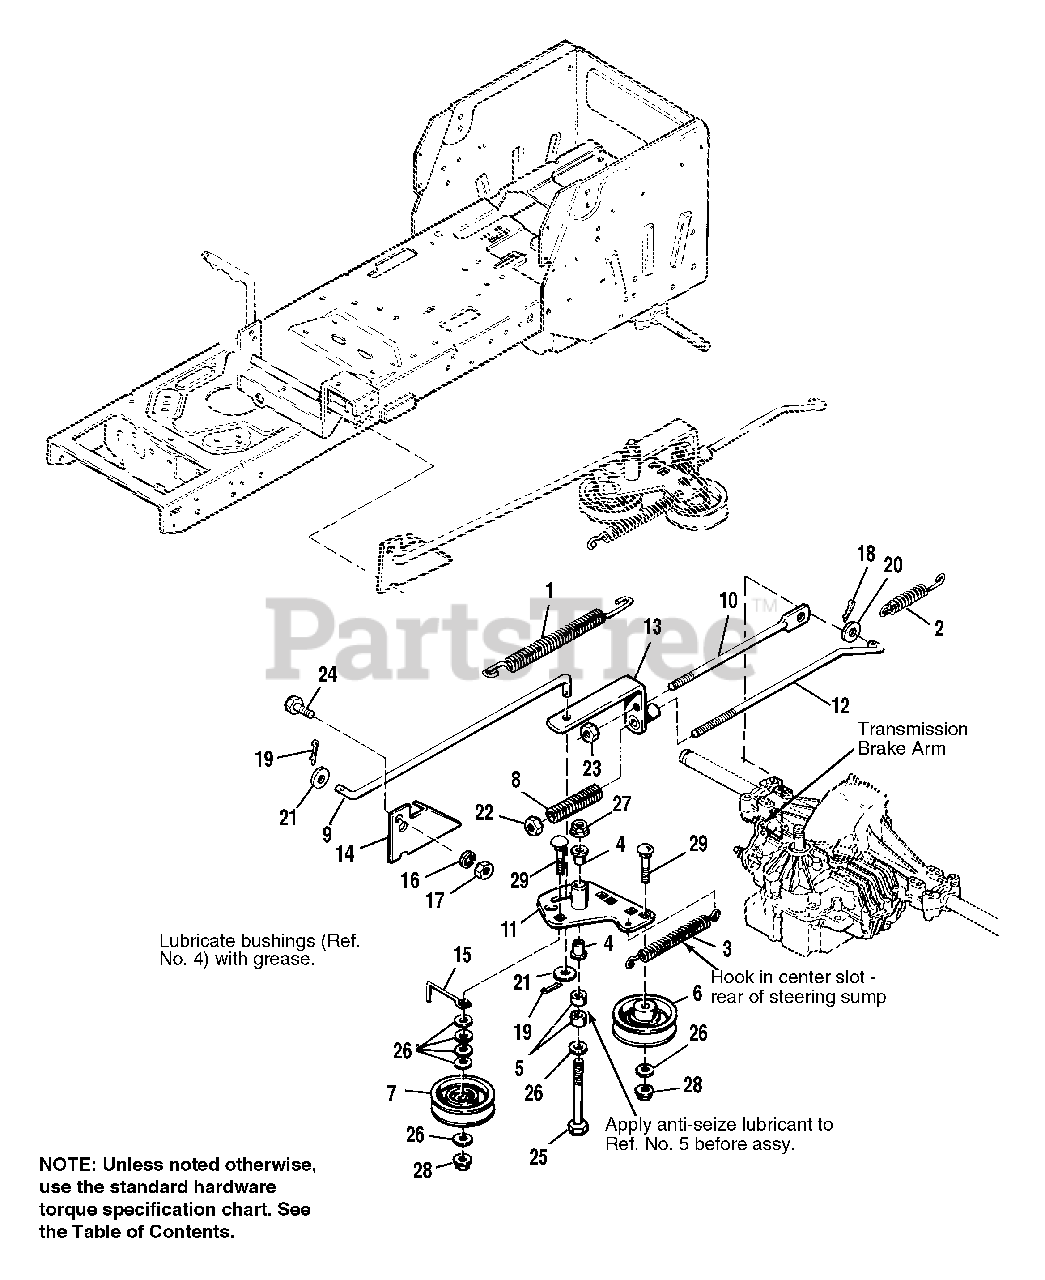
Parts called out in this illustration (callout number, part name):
1	SPRING, External
2	SPRING, External
4	BUSHING, Plastic
6	PULLEY, Idler
7	PULLEY, "V"
9	ROD, Clutch
10	ROD, Return
11	IDLER ARM ASSY.
13	BRAKE ARM ASSY.
14	ACTUATOR, Switch
16	LOCKWASHER, Spring, 3/8
17	NUT, Hex, 3/8-16
18	COTTER PIN, 3/32 x 3/4
19	COTTER PIN, 3/32 x 3/4
20	WASHER, Plain, 11/32 x 3/4 x 1/16
21	WASHER, Plain, 11/32 x 3/4 x 1/16
22	NUT, Hex, Esna, Lock, 3/8-16
23	NUT, Hex, Esna, Lock, 3/8-16
24	CAPSCREW, Hex Hd., 5/16-18 x 3/4
25	CAPSCREW, Hex Hd., 3/8-16 x 3
26	WASHER, 13/32 X 7/8 X 5/64
27	NUT, Flange, Whizlock, 3/8-16
28	NUT, Flange, Whizlock, 3/8-16
29	CARRIAGE BOLT, 3/8-16 x 1-3/4
